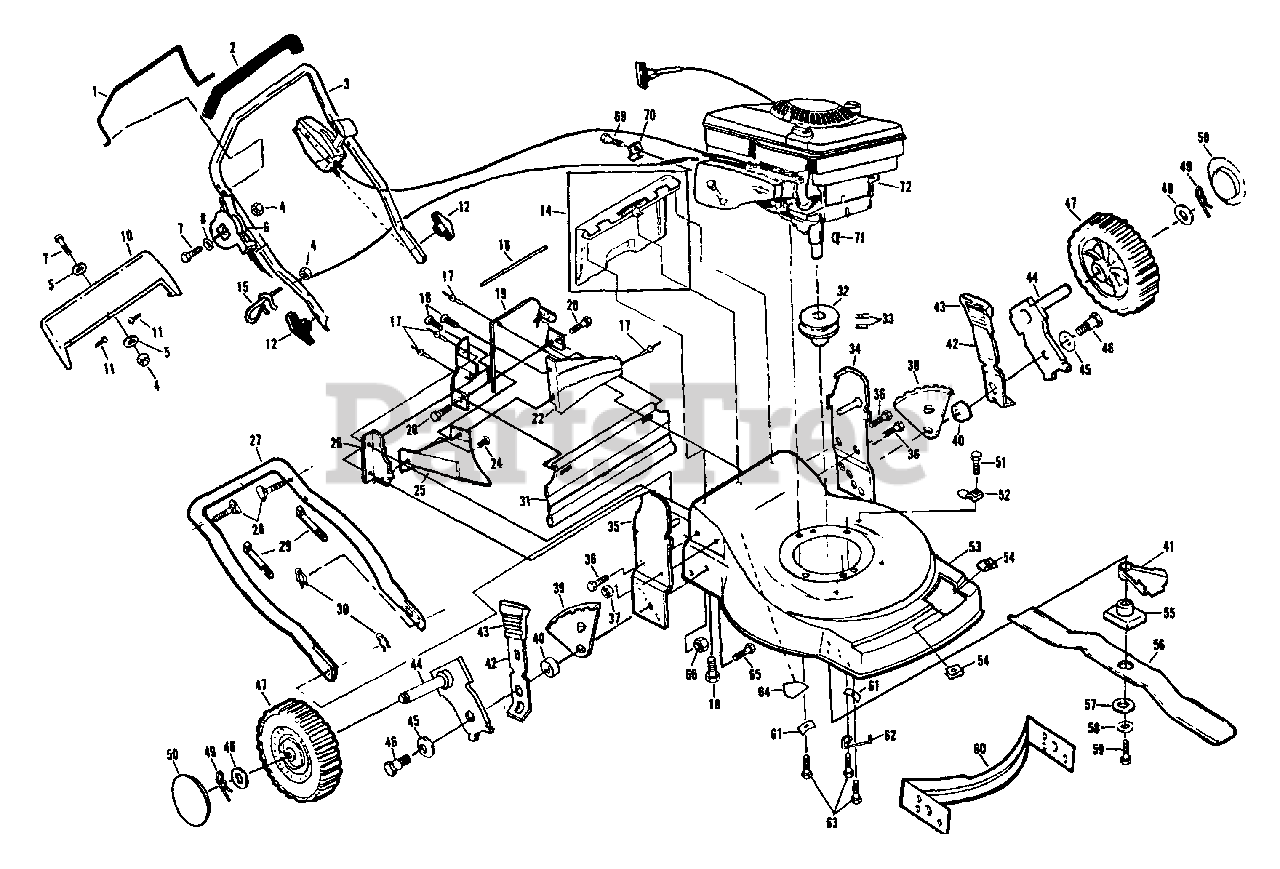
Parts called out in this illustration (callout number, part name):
1	Control Bar
2	Handle Grip
3	Upper Handle
4	Locknut 1/4-20
5	Washer
6	Throttle Control
7	Machine Screw 1/4-20 x 1
8	Flat Washer
10	Trim Plate
11	Self-tapping Screw #10-24 x 5/8
12	Handle Knob
14	Rear Door Asm.
15	Rope Guide
18	Hex Tapping Screw 1/4-20 x 1/2
19	Back Plate
20	Hinge Screw
22	Rear Baffle
24	Hex Head Screw #10-24 x 1/2
25	Discharge Baffle
26	Side Baffle
27	Lower Handle
28	Handle Bolt
29	Wire Tie
30	Hairpin Cotter
31	Rear Skirt
32	Engine Pulley
33	Set Screw 1 /4-20 x 5/16
34	Handle Bracket Assembly (Left)
35	Handle Bracket Assembly (Right)
36	Thread Cutting Screw 5/16-18 x 3/4
37	Locknut 5/16-18
38	Wheel Adjusting Bracket (Left Rear)
39	Wheel Adjusting Bracket (Right Rear)
40	Spacer
41	Shield Debris
42	Selector Spring
43	Selector Knob
44	Axle Arm Assembly
45	Belleville Washer
46	Shoulder Bolt 3/8-16
47	Wheel & Tire Assembly 9.0 x 2.0
48	Washer
49	Retainer Clip
51	Hex Washer Head Screw #10-24 x 1/2
52	Guide Clip
53	Lawn Mower Housing
54	Speed Nut, U Type
55	Blade Adapter
56	22" Blade
57	Hardened Washer
58	Helical Lockwasher 3/8
59	Hex Head Screw 3/8-24 x 1-3/8
60	Front Baffle
61	Engine Washer
62	Retainer Ring Debris Shield
63	Hex Head Thread Rolling Screw 3/8-16 x 1
64	Danger Decal
65	Carriage Bolt 5/16-18 x 5/8
66	Locknut 3/8-16
69	Thread Rolling Screw #10-32 x 5/8
70	Cable Clamp
71	Hi-Pro Key #HP-505
72	Engine
